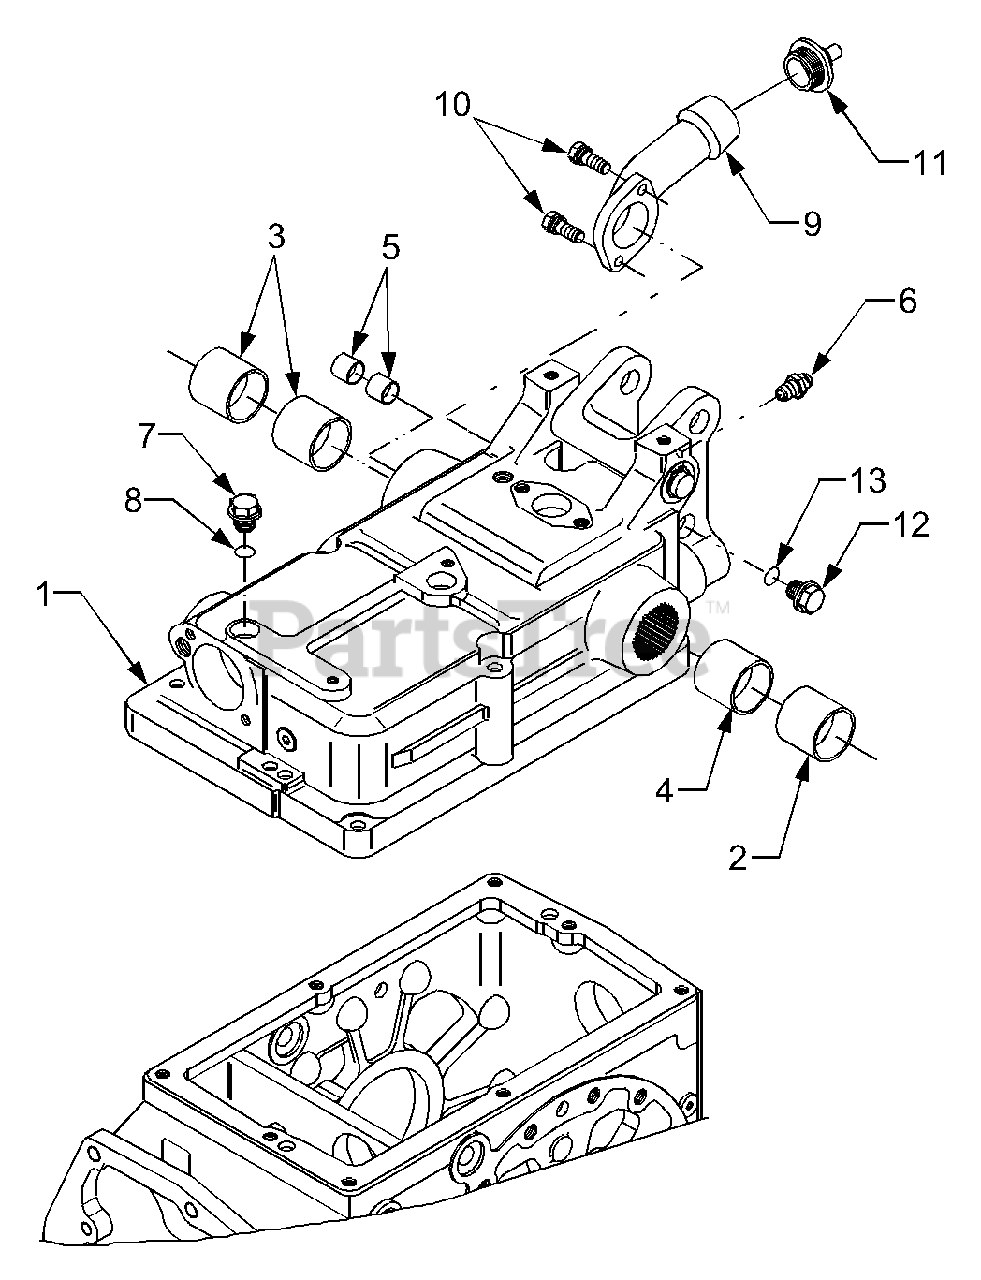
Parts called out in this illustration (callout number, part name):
1	Transmission Cover Plate
6	Nipple, Grease
11	Breather, Air
